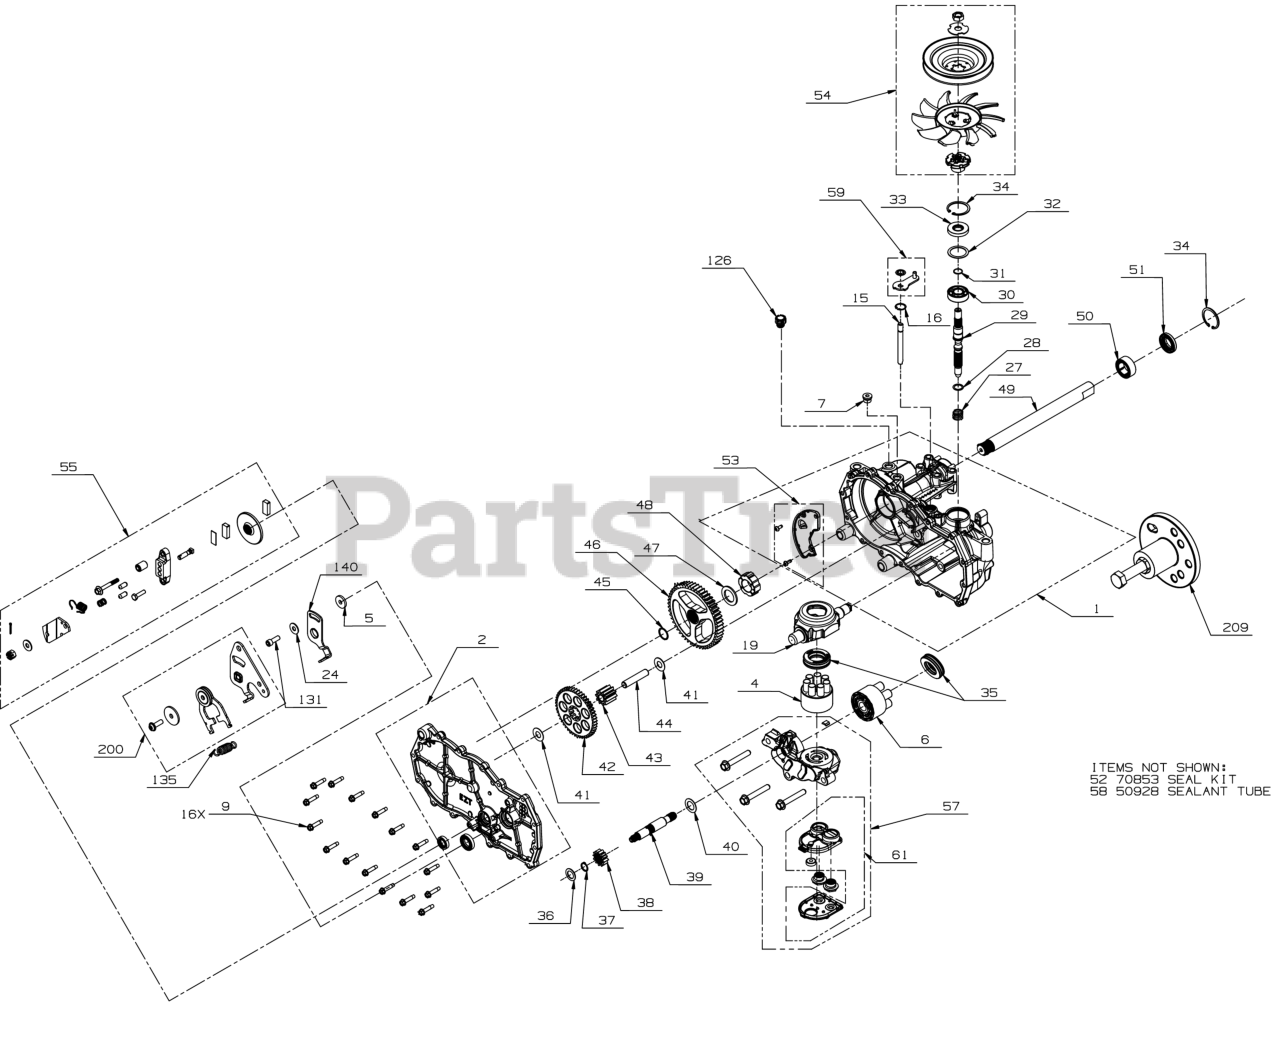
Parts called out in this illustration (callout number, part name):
1	HOUSING ASSEMBLY-MAIN
2	SIDE ASSEMBLY
4	BLOCK KIT-7 PISTON
5	SPACER .32 x 1.005 x .179
6	BLOCK KIT-5 PISTON
7	PLUG-STRAIGHT THRE
9	SCREW-WASHER HEAD
15	BYPASS RODS
16	RETAINING RING
19	SWASHPLATE-TRUNNION
24	FLAT WASHER
27	SPRING-BLOCK
28	THRUST WASHER
29	INPUT SHAFT
30	BALL BEARING
31	RETAINING RING
32	WASHER 1.23X1.56X
34	RETAINING RING
35	THRUST BEARING
36	FLAT WASHER
37	RETAINING RING
38	PINION GEAR 12T
39	MOTOR SHAFT
40	MOTOR SHAFT WASHER
42	GEAR 10T/49T
43	GEAR-10T JACKSHAFT
44	PIN-JACKSHAFT
45	RETAINING RING
46	GEAR-BULL 52T
47	WASHER 1.018 x 1.
48	SLEEVE BEARING
49	AXLE SHAFT 1.00 X
50	SLEEVE BEARING
53	PLATE KIT (LH) EXPANSI
54	KIT-FAN & PULLEY
55	BRAKE KIT-DISC
57	SECTION KIT-CENTER
58	SEALANT-HOUSING
59	ARM KIT-BYPASS
61	FILTER ASSEMBLY
126	BREATHER FITTING 9/16-18
131	SCREWS KIT-RTN
135	EXTENSION SPRING
140	ARM-NEUTRAL (RH)
200	RETURN KIT-NEUTRAL (RH) ZT2800 RZT
209	PULLER KIT-HUB
